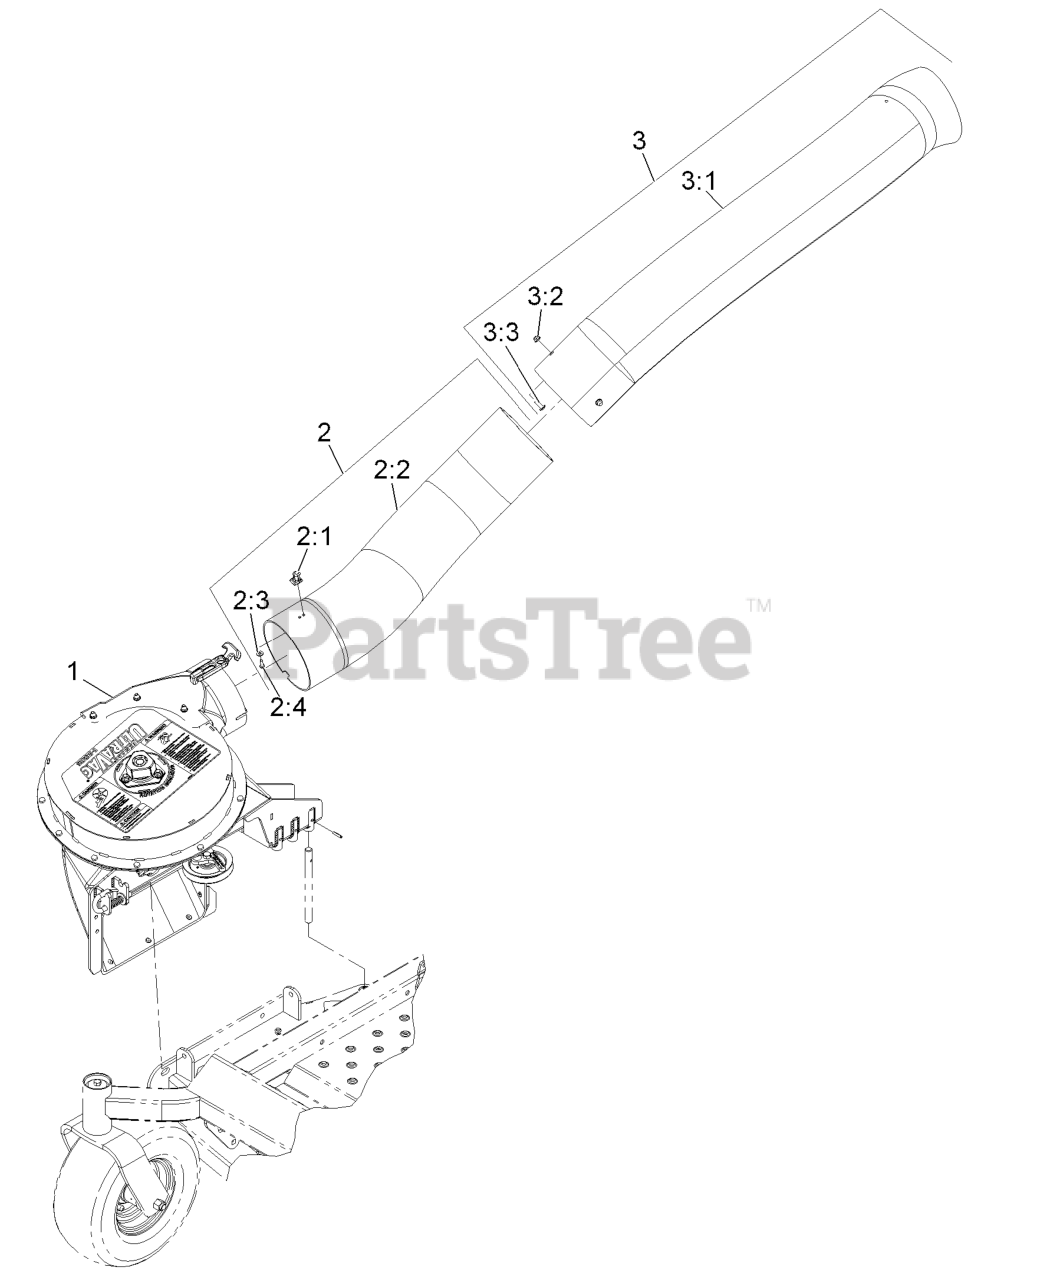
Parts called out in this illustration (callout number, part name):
2	LOWER TUBE ASM
2:1	TUBE-LOWER
2:2	LATCH-KEEPER
2:3	WASHER-FLAT
2:4	SCREW-PPH
3	UPPER TUBE ASM
3:1	TUBE-UPPER
